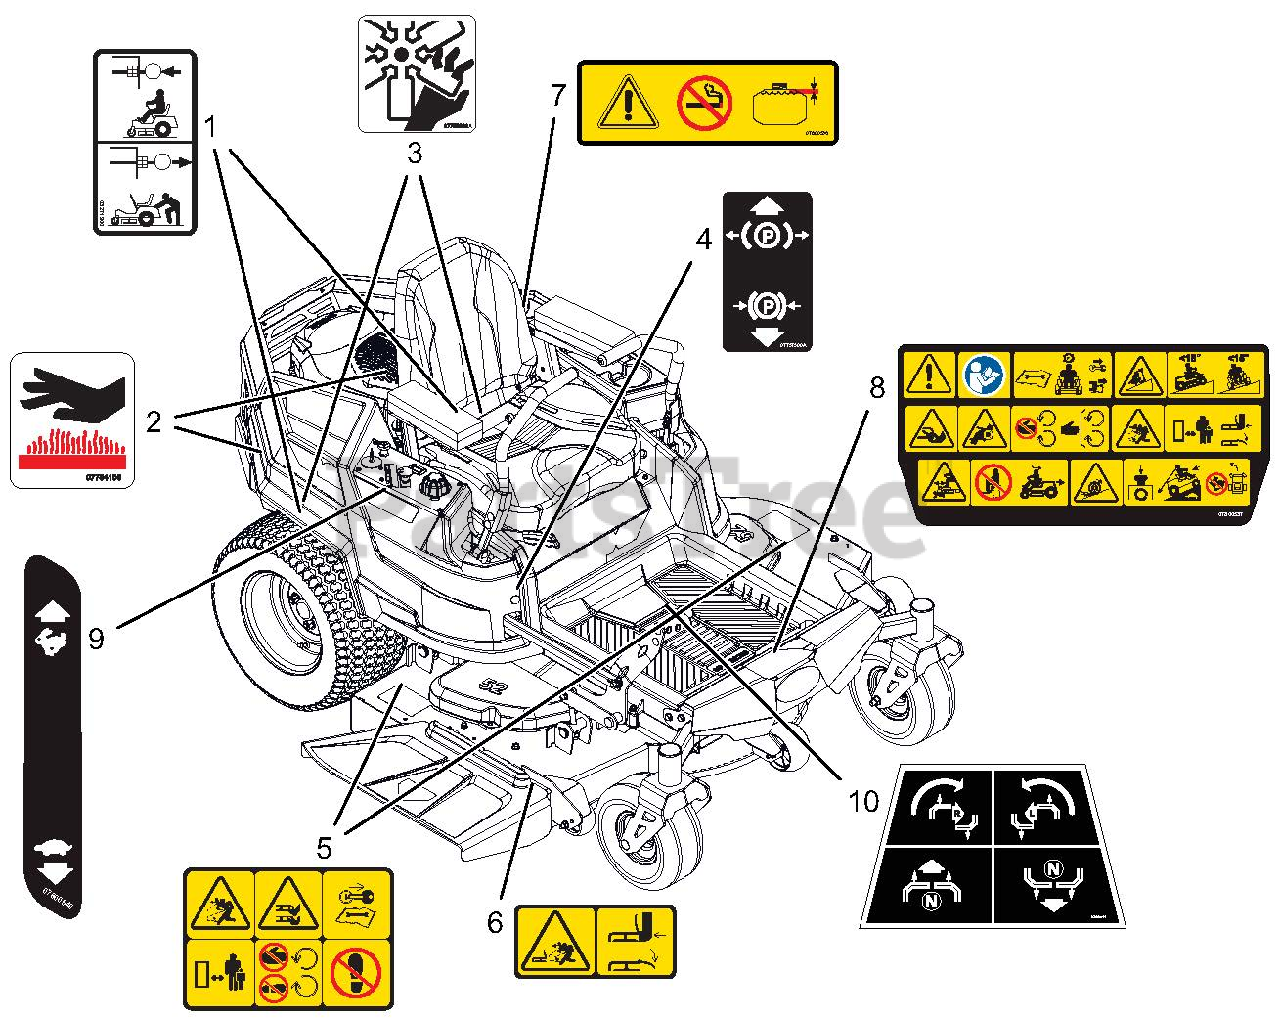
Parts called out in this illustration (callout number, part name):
1	DECAL, TRANSMISSION DISCONNECT
2	DECAL, HOT SURFACE
3	DECAL, DANGER FAN
4	DECAL, PARKING BRAKE LEVER
5	DECAL, SAFETY - MOWER DECK
6	DECAL, SAFETY - DECK GUARDING
7	DECAL-FUEL, WARNING
8	DECAL, MAIN SAFETY
9	DECAL, DASH DECAL
10	DECAL, STEERING
